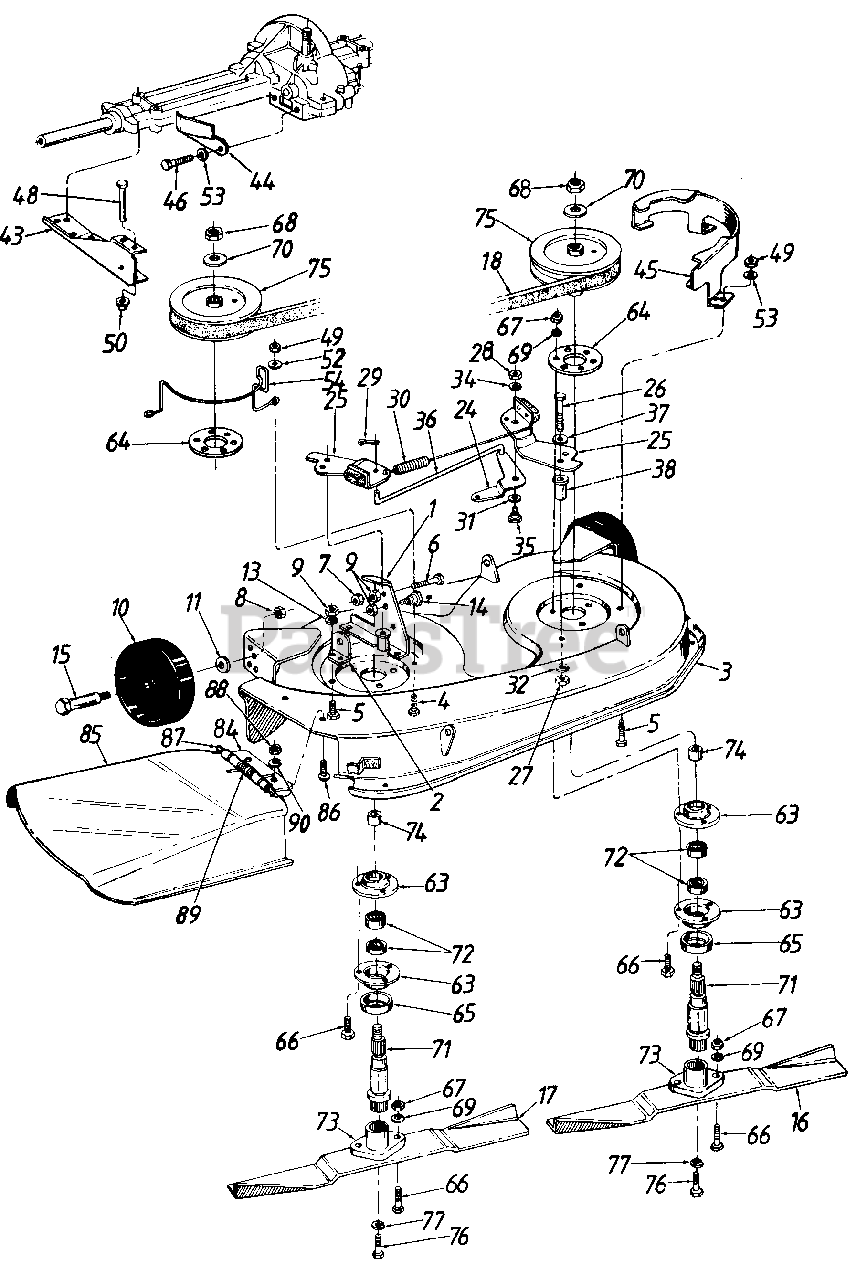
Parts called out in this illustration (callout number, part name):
1	Deck Disengagement Brkt.
2	Rear Deck Brkt.-R.H.
3	32" Deck Ass'y.
4	Hex Bolt 1/4-20 x .75" Lg.
5	Hex Bolt 1/4-20 x .62" Lg.
6	Hex Wash. Hd. Scr. 1/4-20 x 1.5" 19.
7	Hex L-Nut 1/4-20 Thd.
8	Hex L-Nut 3/8-16 Thd.
9	Hex Nut 1/4-20 Thd.
10	Deck Wheel
11	Bell-Wash. .380" I.D. x .88
13	L-Wash. 1/4" I.D.
14	Shld Bolt .500" Dia. x .215" Lg.
15	Shld Bolt .498" Dia. x 1.53" Lg.
16	L.H. High-Lift Blade
17	R.H. High-Lift Blade
18	V-Belt
24	Deck Brake Bracket
25	Deck Brake Brkt. Ass'y.
26	Hex Bolt 5/16-24 x 2" Lg.
27	Hex Nut 5/16-24 Thd.
28	Hex Nut 1/4-20 Thd.
29	Cotter Pin 1/16" Dia.
30	Extension Spring
31	Fl-Wash. .406" I.D. x 1.0" O.D.
32	L-Wash. 5/16" I.D.
34	L-Wash. 1/4" I.D.
35	Shld Bolt .375" Dia. x .181" Lg.
36	Deck Control Rod
37	Shld. Spacer x .27" Lg.
38	Spacer 1.46" Lg.
43	Lower Outside Belt Guard
44	Lower Inside Belt Guard
45	Belt Guard Deck-R.H.
46	Hex Bolt 1/4-20 x .62" Lg.
49	Hex Nut 1/4-20 Thd.
50	Speed Nut 1/4 Rod
52	Bell-Wash. .265" I.D. x .75
53	L-Wash. 1/4" l.D.*
54	Deck Belt Guard
63	Bearing Housing
64	Reinforcement Plate
65	Bearing Shield
66	Hex Bolt 5/16-24 x 1.0" Lg. (Special)
67	Hex Nut 5/16-24 Thd.*
68	Hex Jam Nut 5/8-18 Thd.
69	L-Wash. 5/16" I.D.
70	L-Wash. 5/8" I.D.
71	Blade Spindle
72	Ball Bearing
73	Blade Adapter
75	5" Dia. Pulley
76	Hex Bolt 3/8-24 x 1.0" Lg.
77	L-Wash. 3/8" I.D. H.D.
84	Chute Bracket
85	Chute
86	Truss.-Mach. Scr. 1/4-20 x .75" Lg.
87	Hinge Pin
88	Hex Nut 1/4-20 Thd.*
89	Torsion Spring 1.14" Lg.
90	L-Wash. 1/4" I.D.*
